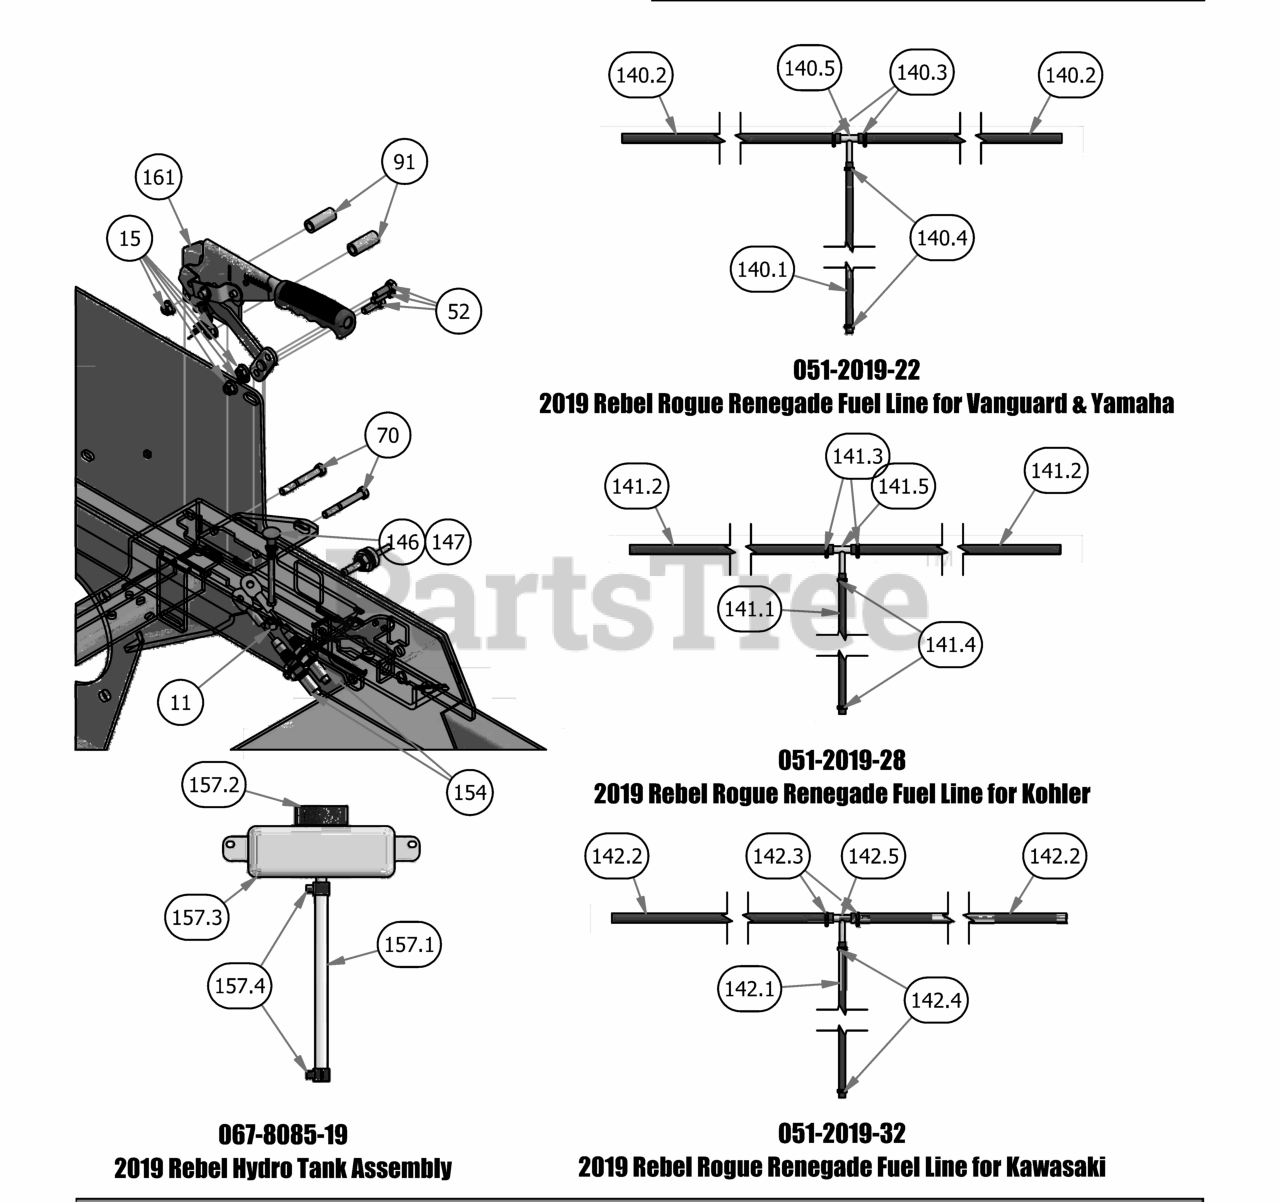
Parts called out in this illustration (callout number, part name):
140.1	1/4" Fuel Line Hose
140.2	5/16" fuel line hose
140.3	5/16 Fuel Line Clamp
140.4	1/4 Fuel Hose Clamp
140.5	5/16 x 5/16 x 1/4 Fuel Line T
141.1	1/4" Fuel Line Hose
141.2	5/16" fuel line hose
141.3	5/16 Fuel Line Clamp
141.4	1/4 Fuel Hose Clamp
141.5	5/16 x 5/16 x 1/4 Fuel Line T
142.1	1/4" Fuel Line Hose
142.2	5/16" fuel line hose
142.3	5/16 Fuel Line Clamp
142.4	1/4 Fuel Hose Clamp
142.5	5/16 x 5/16 x 1/4 Fuel Line T
157.1	5/8 Braided Hose
157.2	Hydraulic Tank Cap
157.3	Expansion Tank Outlaw
157.4	5/8 Wire Clamp-Outlaw Only
